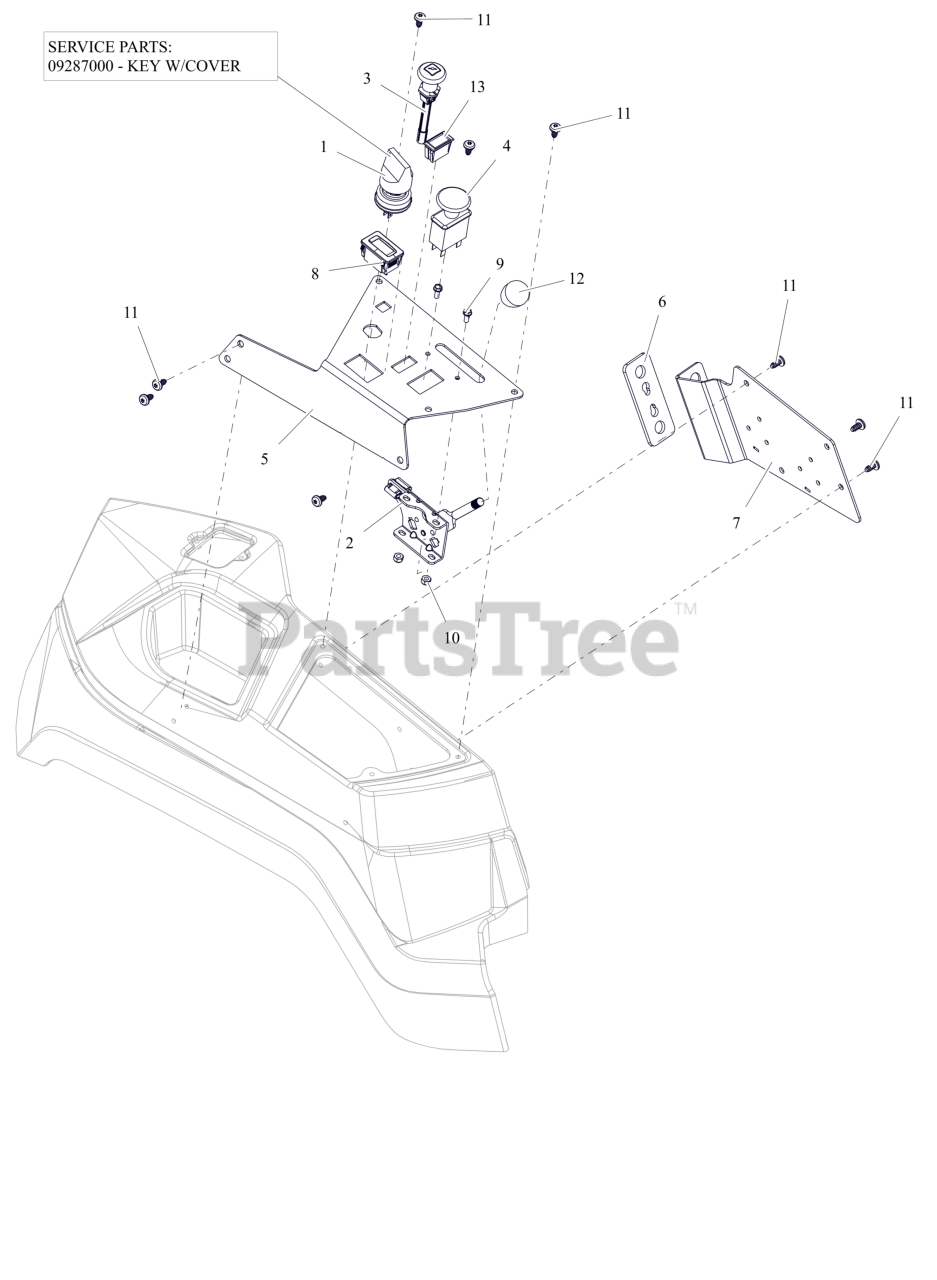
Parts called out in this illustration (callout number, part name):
1	SWITCH, IGNITION
1	KEY, W/ SHIELD
2	CABLE, PRO THROTTLE CONTROL
3	CABLE - CHOKE, SNAP-IN
4	SWITCH, CLUTCH
5	PLATE, APEX CONTROL PANEL
6	PLATE, CONTROL PANEL SPACER
7	BRKT, FENDER/RELAY MOUNTING
8	HOUR METER
9	BLT, HWH #10-24X.50 ZCC
10	NUT-LK-NYL #10-24 G2 ZCC
11	SCR-PAN .25-15X.50 6L H/LZB500
12	KNOB-CONTROL-BLACK .38-16X.50
13	SWITCH,BLANK
